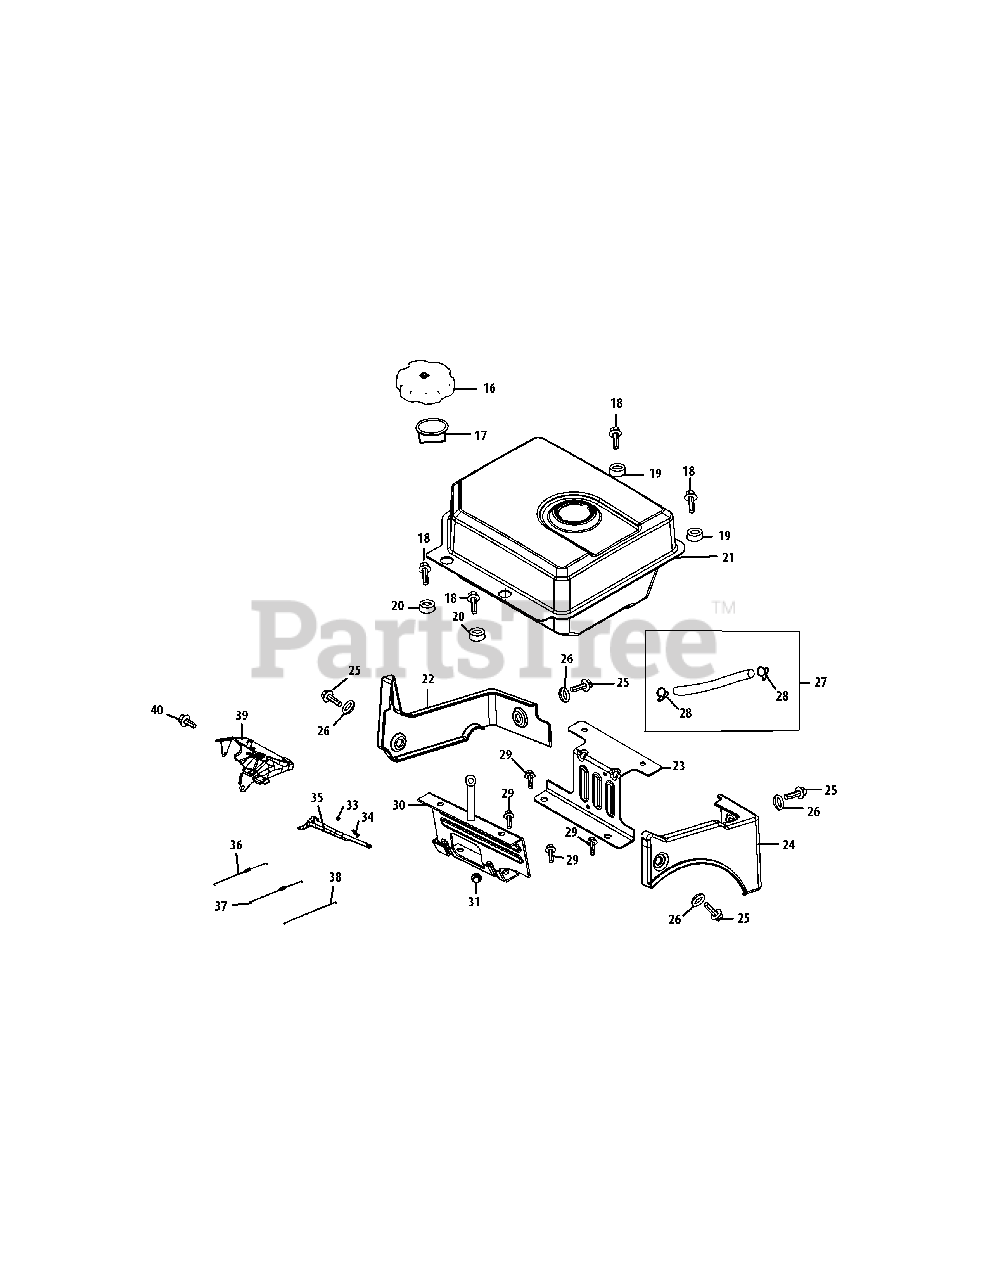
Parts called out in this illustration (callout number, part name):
16	Fuel Cap Assembly
17	Fuel Level Indicator
18	Bolt M8×20
19	Bushing I, Gas Tank
20	Bushing II, Gas Tank
21	Fuel Tank Assembly
22	Fuel Tank Shroud
23	Fuel Tank Mounting Bracket
24	Engine Shroud
25	Bolt M6×16
26	Flat Washer
27	Fuel Line Kit
28	Fuel Hose Clamp
29	Bolt M8×14
30	Gas Tank Support Bracket
33	Nut M6
34	Governor Arm Bolt
35	Governor Arm
36	Governor Spring
37	Throttle Return Spring
38	Governor Rod
39	Throttle Control Asm
40	Bolt,M6×14
